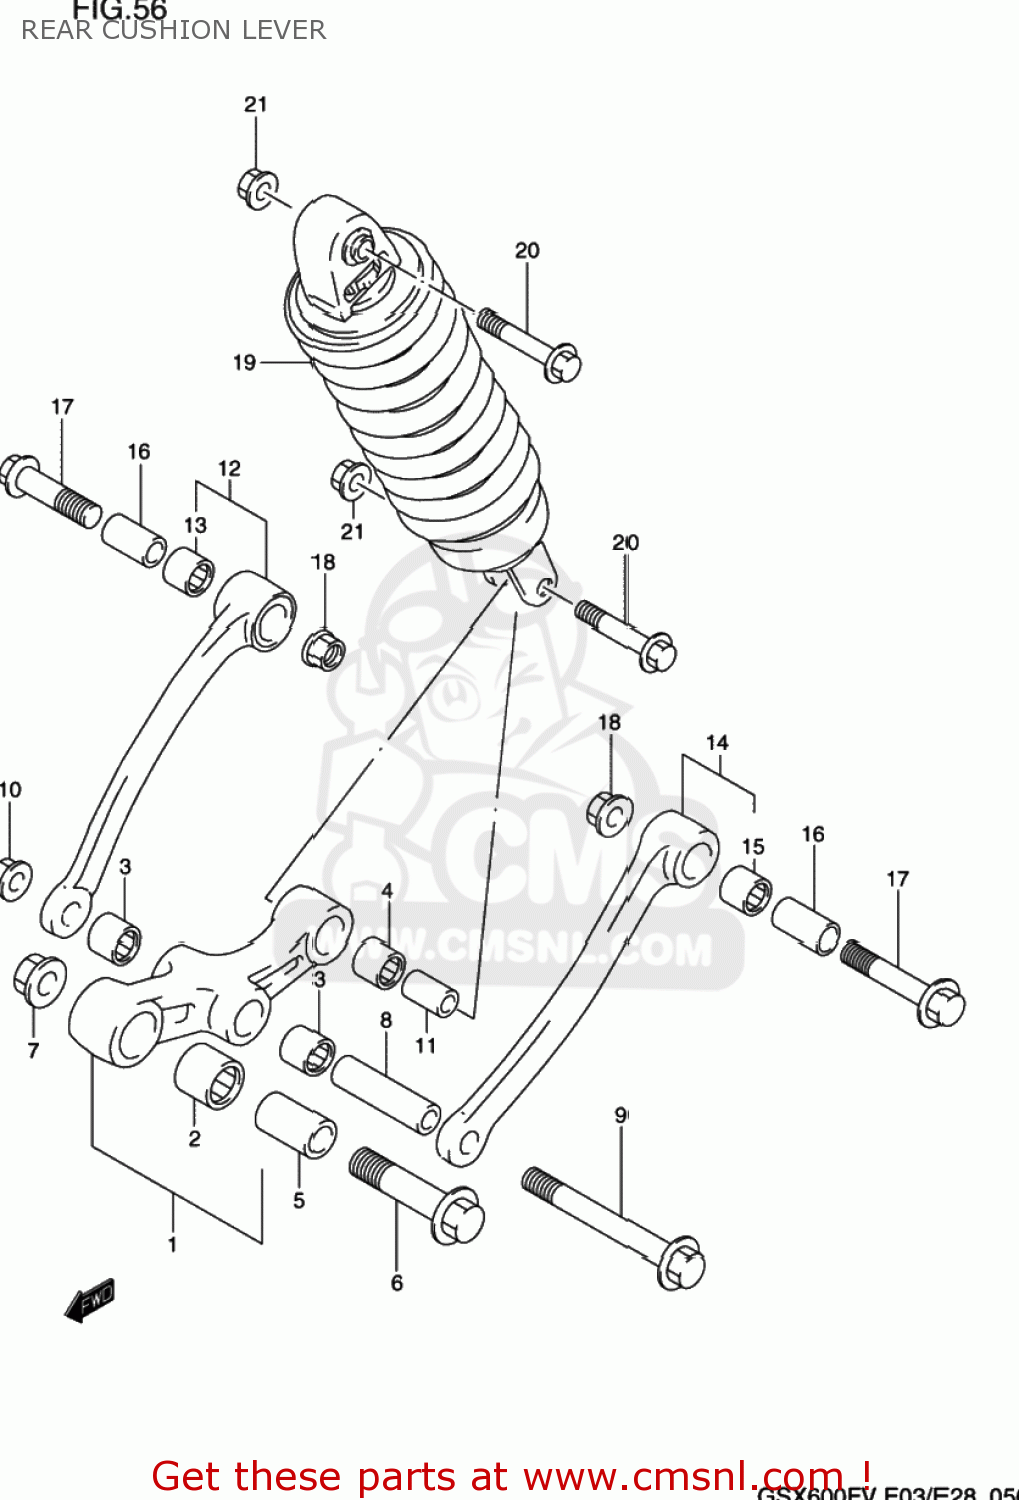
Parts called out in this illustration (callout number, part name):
1	LEVER SET,RR CUSHION
2	BEARING(20X27X30)
3	BEARING(17X24X25)
4	BEARING(17X24X26)
5	SPACER(14X20X34)
6	BOLT(14X62)
7	NUT 14MM
8	SPACER(12X17X60)
9	BOLT(12X96)
10	NUT 12MM
11	SPACER,RR CUSHION LEVER
12	ROD SET,RR CUSHION,R
13	BEARING(17X24X26)
14	ROD SET,RR CUSHION,L
15	BEARING(17X24X26)
16	SPACER(12X17X29)
17	BOLT L:52
18	NUT 12MM
19	ABSORBER ASSY,RR SHOCK
20	BOLT(10X52)
21	NUT 10MM
